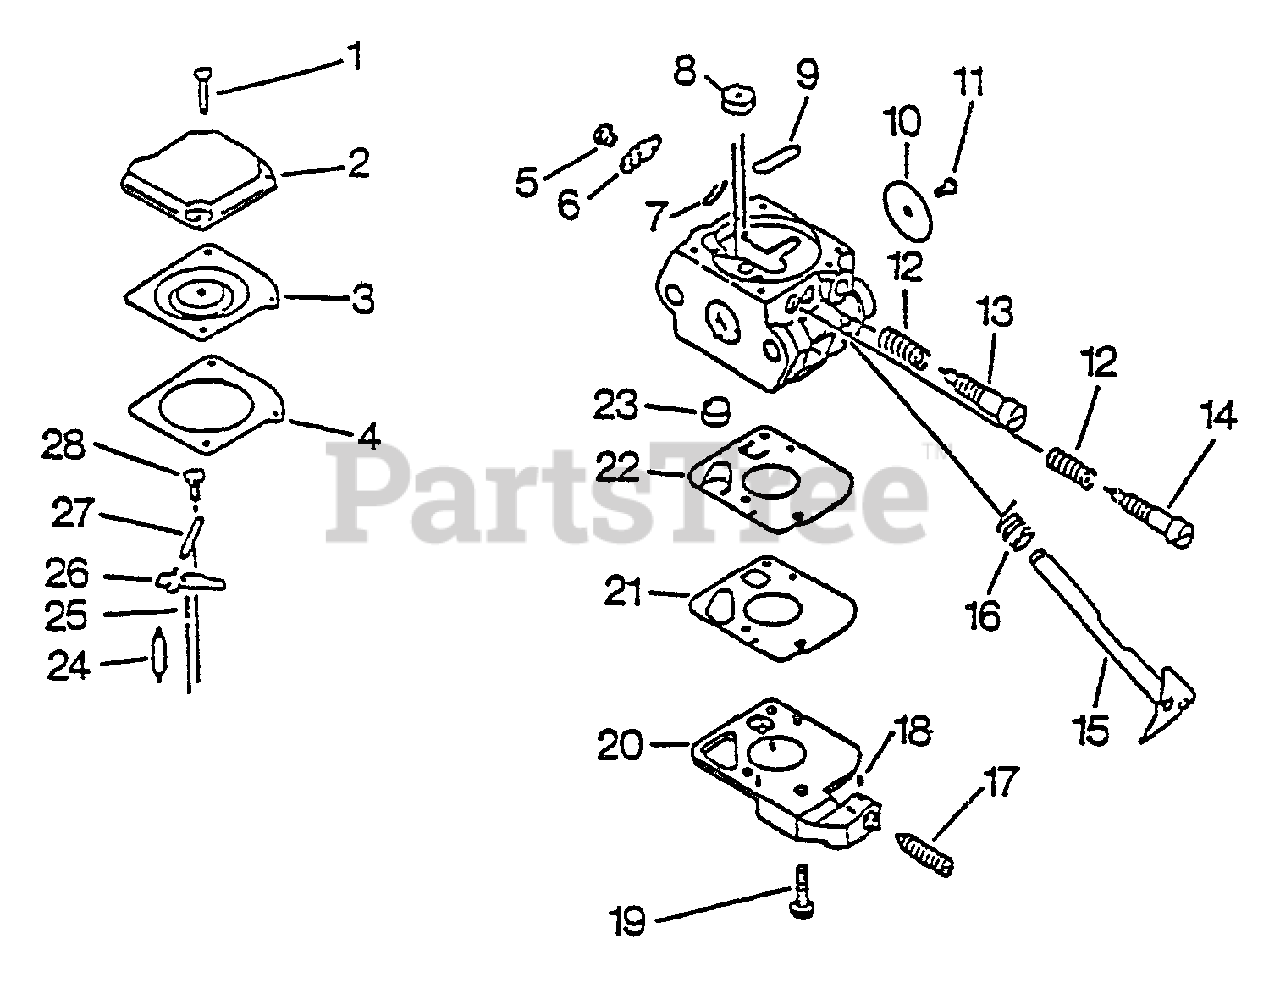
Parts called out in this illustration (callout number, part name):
2	COVER, METERING
3	DIAPHRAGM
4	GASKET, METERING
6	LEVER, THROTTLE
7	RING, RETAINING
8	ORIFICE, MAIN FUEL
9	PLUG, WELCH
10	VALVE, THROTTLE
11	SCREW
13	NEEDLE - HIGH SPEED
14	NEEDLE - LOW SPEED
15	SHAFT, THROTTLE
16	SPRING, RETURN
17	SCREW, IDLE ADJUST
18	PIECE, FRICTION
19	SCREW, PUMP COVER
20	BASE, PURGE
21	GASKET, PURGE
22	DIAPHRAGM, PURGE
23	STRAINER
24	VALVE, NEEDLE
25	SPRING
26	LEVER, METERING
27	PIN
28	SCREW, METERING LEVER PIN
